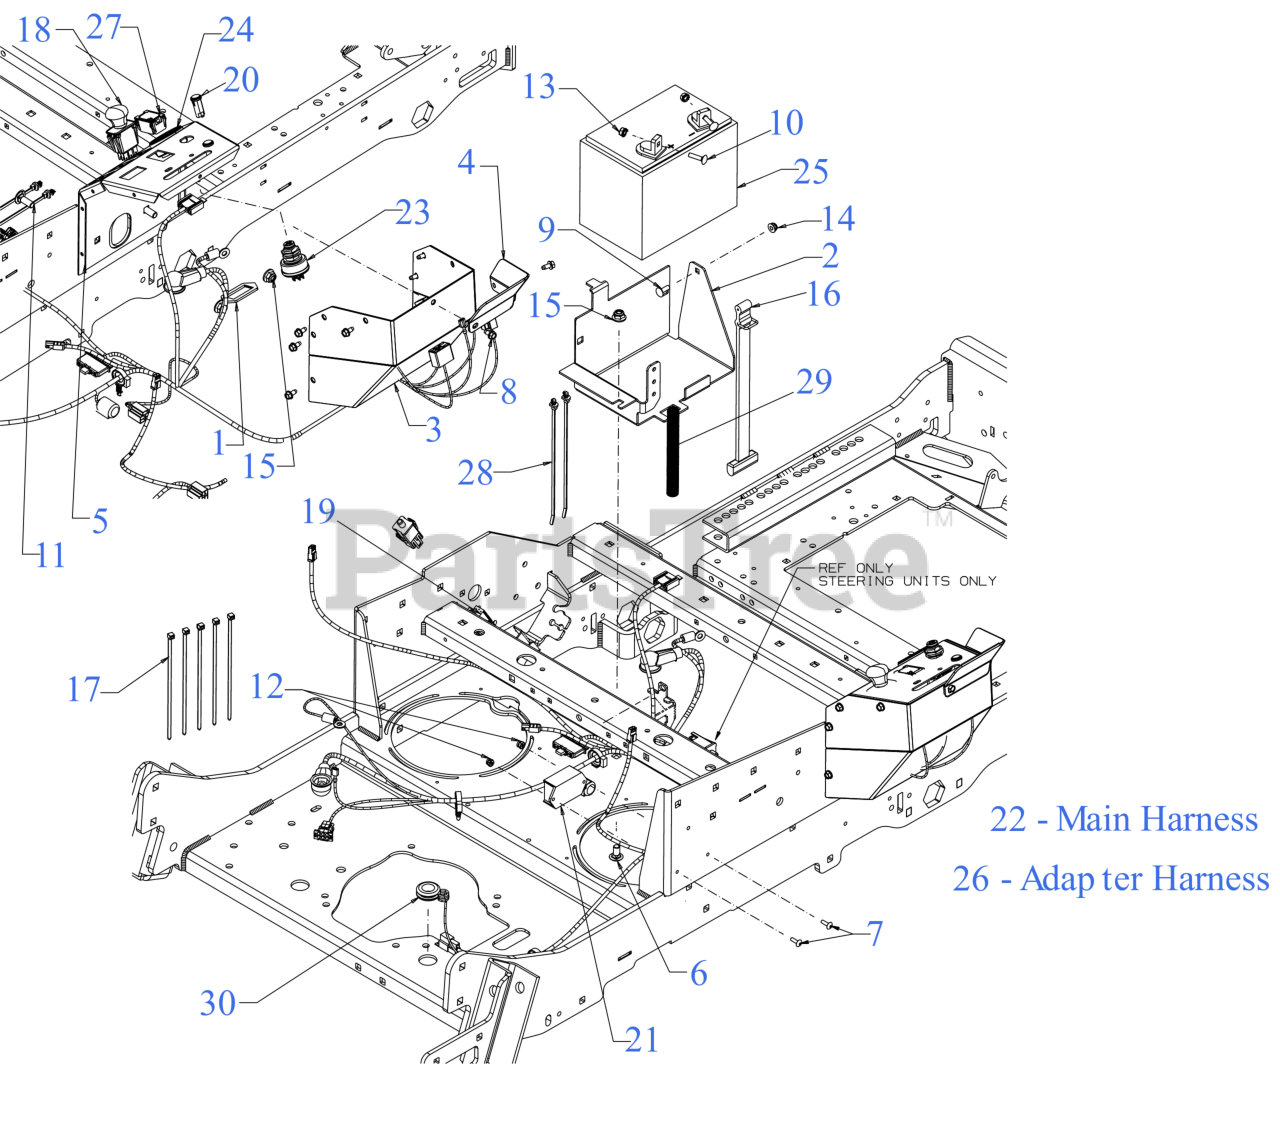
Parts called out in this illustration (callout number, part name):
1	BRACKET-PTO SWITCH
2	BATTERY MOUNTING BRACKET
5	CONTROL POD (RH)
6	CARRIAGE BOLT 3/8-16 x .750 GR5
7	SCREW #10-24 x .62
8	SCREW 1/4-20 X.500
9	SCREW 1/4-20 x .75 GR5
10	SCREW 1/4-20 x 1 GR5
11	CARRIAGE BOLT 3/8-16 x 1.00 GR5
13	SEMS NUT 1/4-20
14	FLANGE LOCK NUT
16	BATTERY RETAINER STRAP
17	7" CABLE TIE
18	PTO SWITCH (BLACK KNOB) TEXT SYM
19	3 POLE SWITCH ( NC-NO-NO)
20	INDICATOR LIGHT-RED
21	CONTROL PANEL (SOFT CLUTCH)
22	WIRE HARNESS ASSEMBLY KOH/KAW EFI
23	KEY SWITCH (3 POSITION)
24	DUAL FUEL GAUGE
25	BATTERY (230 CCA AGM U1-280)
26	HARNESS ADAPTER (KAW EFI)
27	HOUR METER
28	CABLE TIE
29	CONVOLUTED CONDUIT 1"
30	RUBBER GROMMET
